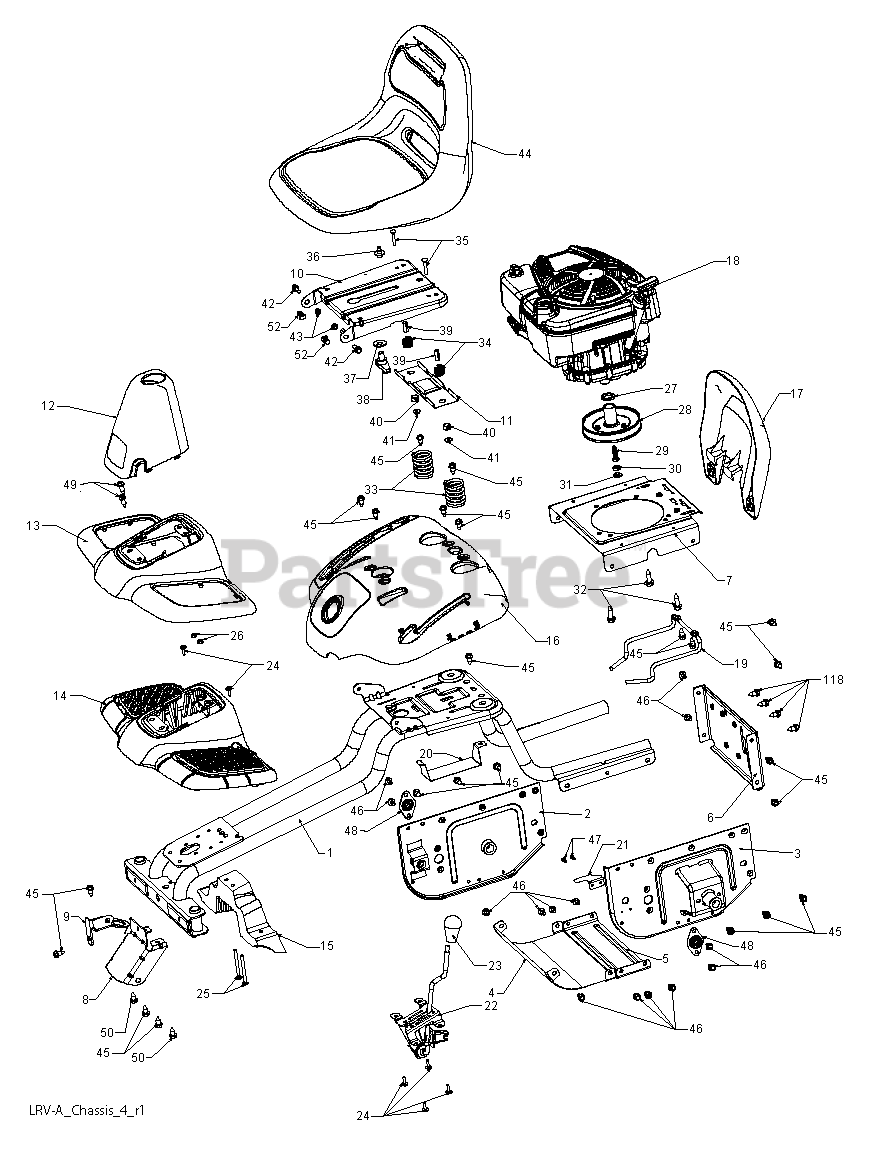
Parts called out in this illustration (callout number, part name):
1	CHASSIS.WLD.26".LRV
2	RP SUPPORT, AXLE RH
3	SUPPORT, AXEL LH
4	SHIELD, TRANSAXLE FRONT
5	STRAP.CROSS.FRICTION.DRIVE
6	COVER, FRICTION DRIVE
7	PLATE, ENGINE
8	BRACKET, CHASSIS FRONT
9	BRACKET, STEERING SUPPORT
10	PAN.ASM.SEAT.1SLOT
11	BRKT.MNTNG.SWITCH.SEAT.BLACK
12	BOOT, DUST LRV (2 2)
13	FOOTREST.AESTHETIC.WE.GRN.LRV
14	STRUCTURE, FOOT REST
15	SUPPORT, FOOT REST
16	FENDER.CNTRL.PNL.WE.GRN.LRV
17	GUARD.ENGINE.LRV
19	KEEPER, BELT
20	BRACKET, BATTERY LRV
21	LEVER, SWITCH
22	CABLE.ASM.CLUTCH.W/BRACKET
23	KNOB.OVAL.CUSTOM.BLACK
24	SCREW.#10 X 0.750.BOS (2 2)
25	BOLT.CARRIAGE
26	NUT
27	SPACER.ENGINE.B&S.LRVA
28	DISC, FRICTION ASM
29	BOLT, SCKT HD 3/8-24 X 1 .25
30	BEARING.BALL.689ZZ
31	SPACER.NEUTRAL
32	BOLT 3/8-16X1-1/8
33	SPRING COMPRESSION
35	BOLT.ROUND.HEAD.SQUARE.NECK
36	BOLT,SHOULD
38	KNOB.SEAT.ADJ.WINGNUT
39	SPACER SPLIT 28X.96
41	NUT T
42	BOLT.SHOULDER.5/16-18
43	NUT.71038.31-18.HEX.NYLOCK
44	SEAT.SUBASY.OPP.WEEDEATER.LRVA
45	SCREW
46	SCREW LT
48	BEARING FLANGE BALL
49	SCREW 5/16-18X1
50	BOLT.SHOULDER.5/16-18X
52	PUSH CLIP
118	SHOULDER BOLT 5/16-18TT
